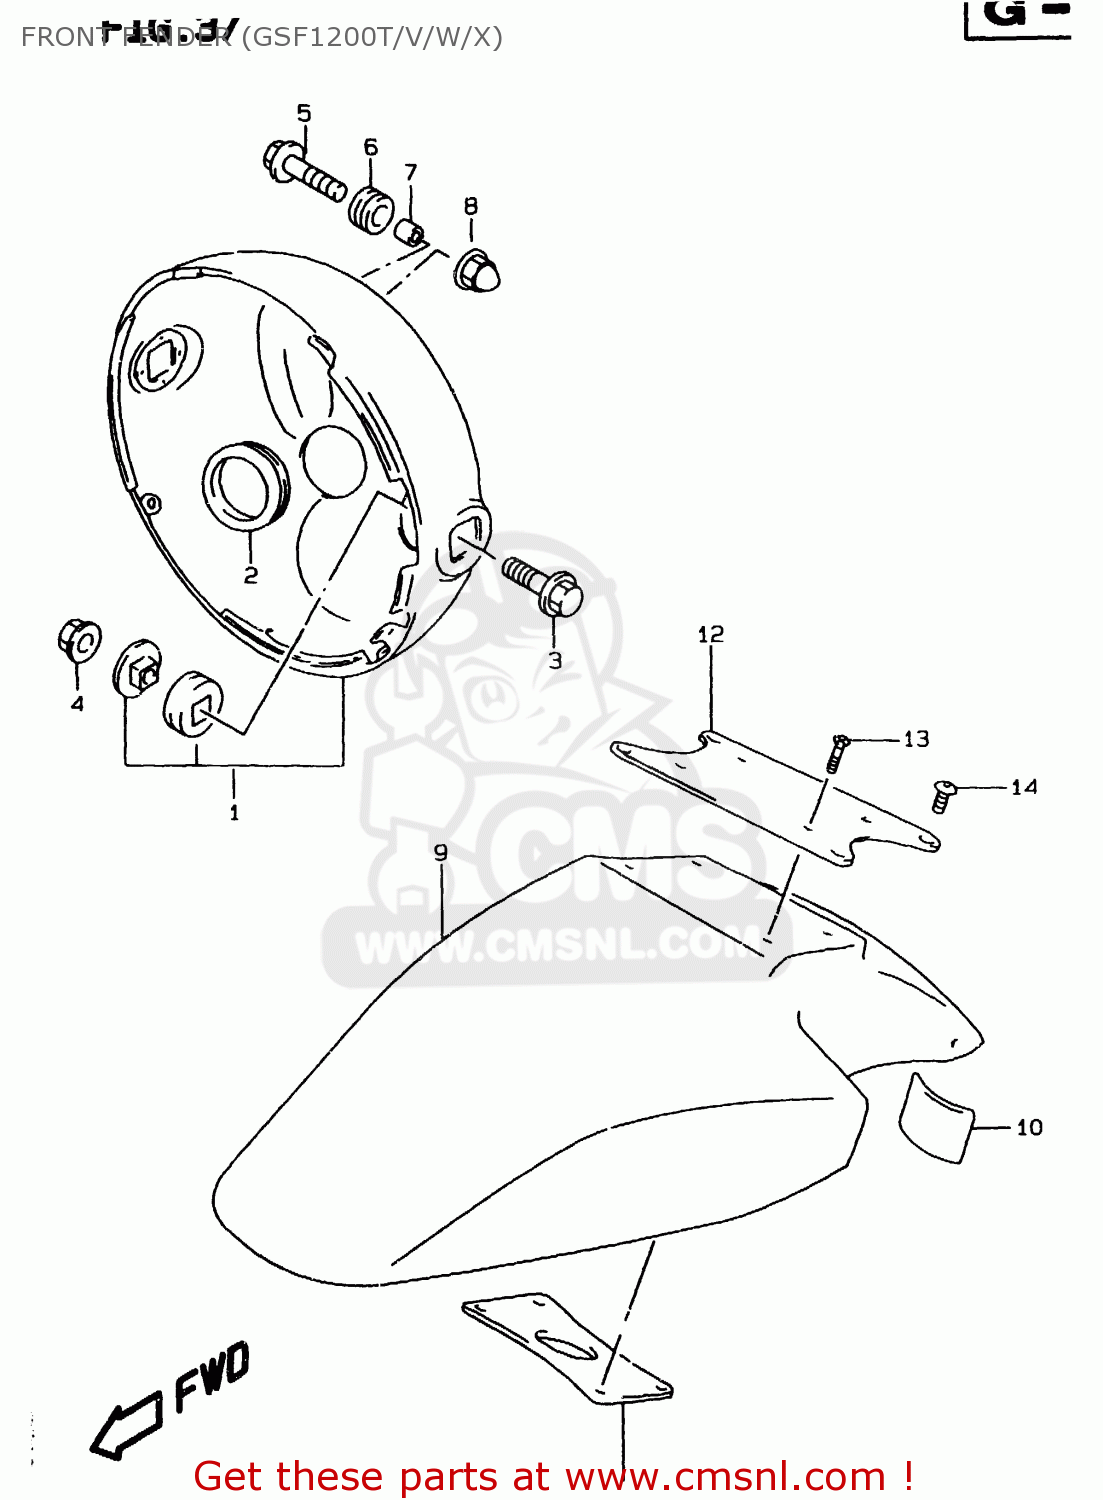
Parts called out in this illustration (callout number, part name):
1	HOUSING,HEADLAMP
2	GROMMET
3	BOLT
4	NUT
5	BOLT
6	CUSHION
7	SPACER(6.5X10.5X12)
8	PLATE,HEADLAMP
9	FENDER,FR
10	CUSHION,FR FENDER
11	BRACE,FR FENDER INNER
12	BRACE,FR FENDER
13	SCREW(5X18)
14	SCREW(8X16)
